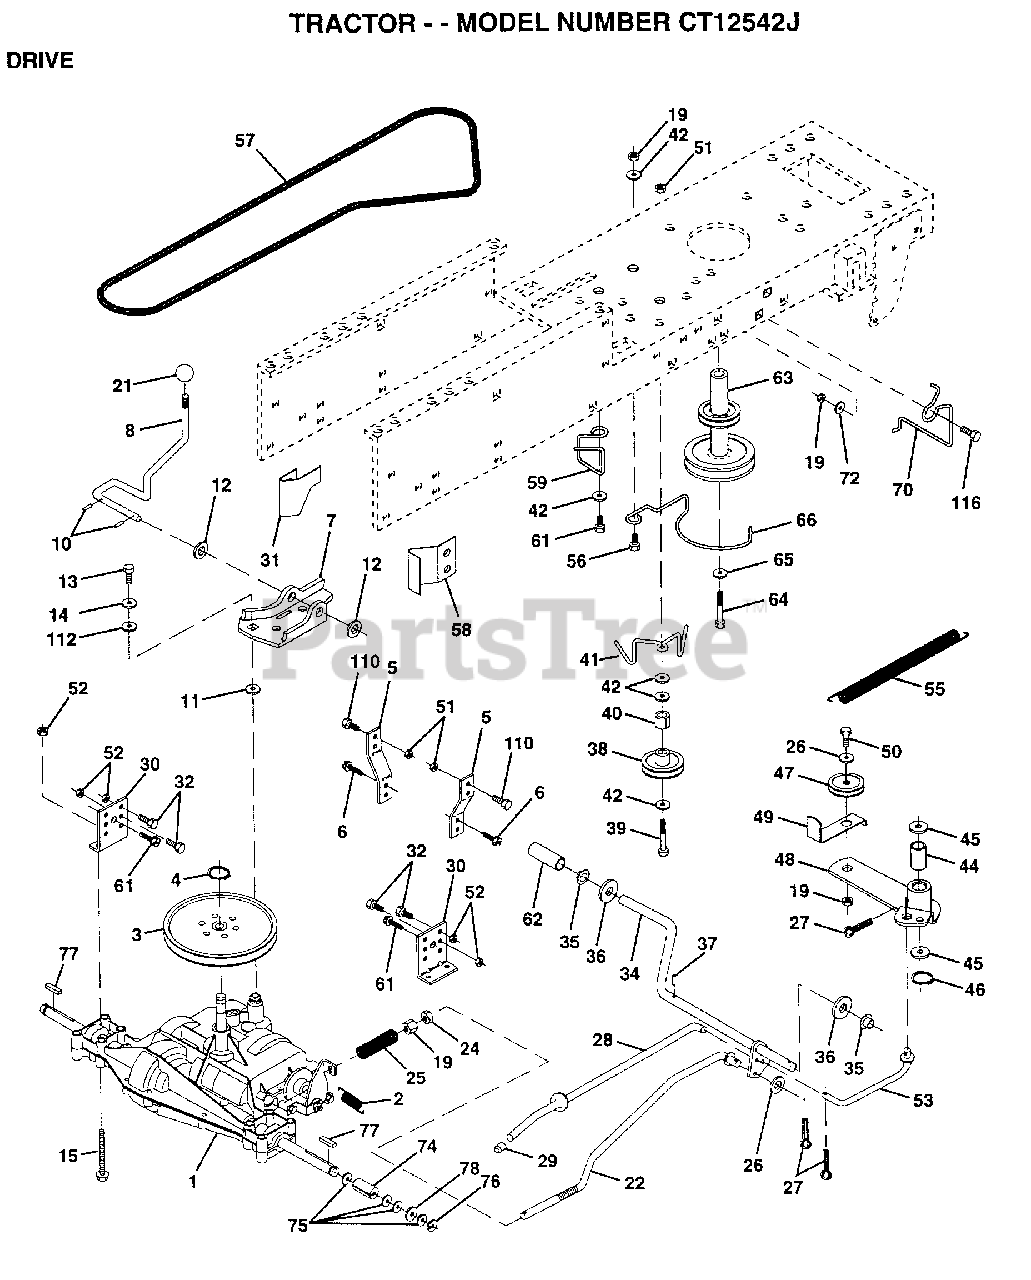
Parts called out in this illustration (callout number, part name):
2	SPRING.BRAKE.RETU
3	PULLEY TRANS
5	STRAP TORQUE
6	SCREW
8	SHIFT ROD
10	PIN COTTER 1/8
11	WASH-SHFT PLT LT
12	WASHER
13	BOLT.1/4-28.W/PAT
14	LOCKWASHER
15	BOLT.HX.FLG.5/16
19	NUT
21	CONTROL KNOB LT
22	BRAKE ROD
24	NUT
25	SPRING ROD LT
26	WASHER
27	COTTER PIN
28	ROD.BRAKE.PARK.LT
30	TRANSAXLE MTG BKT
31	"KEEPER,BELT LH T"
32	BOLT
34	SHAFT FOOT PEDAL
35	NYLON BEARING
36	WASHER LT
38	PULLEY.IDLER.FLAT
39	BOLT
40	SPACER T
41	KEEPER BELT
42	WASHER
44	"LY, BEARING"
45	WASHER LT
46	KLIP RING
48	ARM IDLER
49	RETAIN BELT
53	"LINK, CLUTCH T"
55	"SPRING, RETURN LT"
58	"KEEPER,BELT RH T"
59	KEEPER BELT CNTSP
61	SCREW
62	PEDAL COVER T
63	PULLEY.ENGINE
64	BOLT
65	LOCKWASHER
70	KEEPER BELT ENG
72	WASHER
74	SPACER LT
75	WASHER
76	E-RING LT
77	SQUARE KEY
78	WASHER
112	WASHER LT
116	BOLT RDHD 3/8-16
